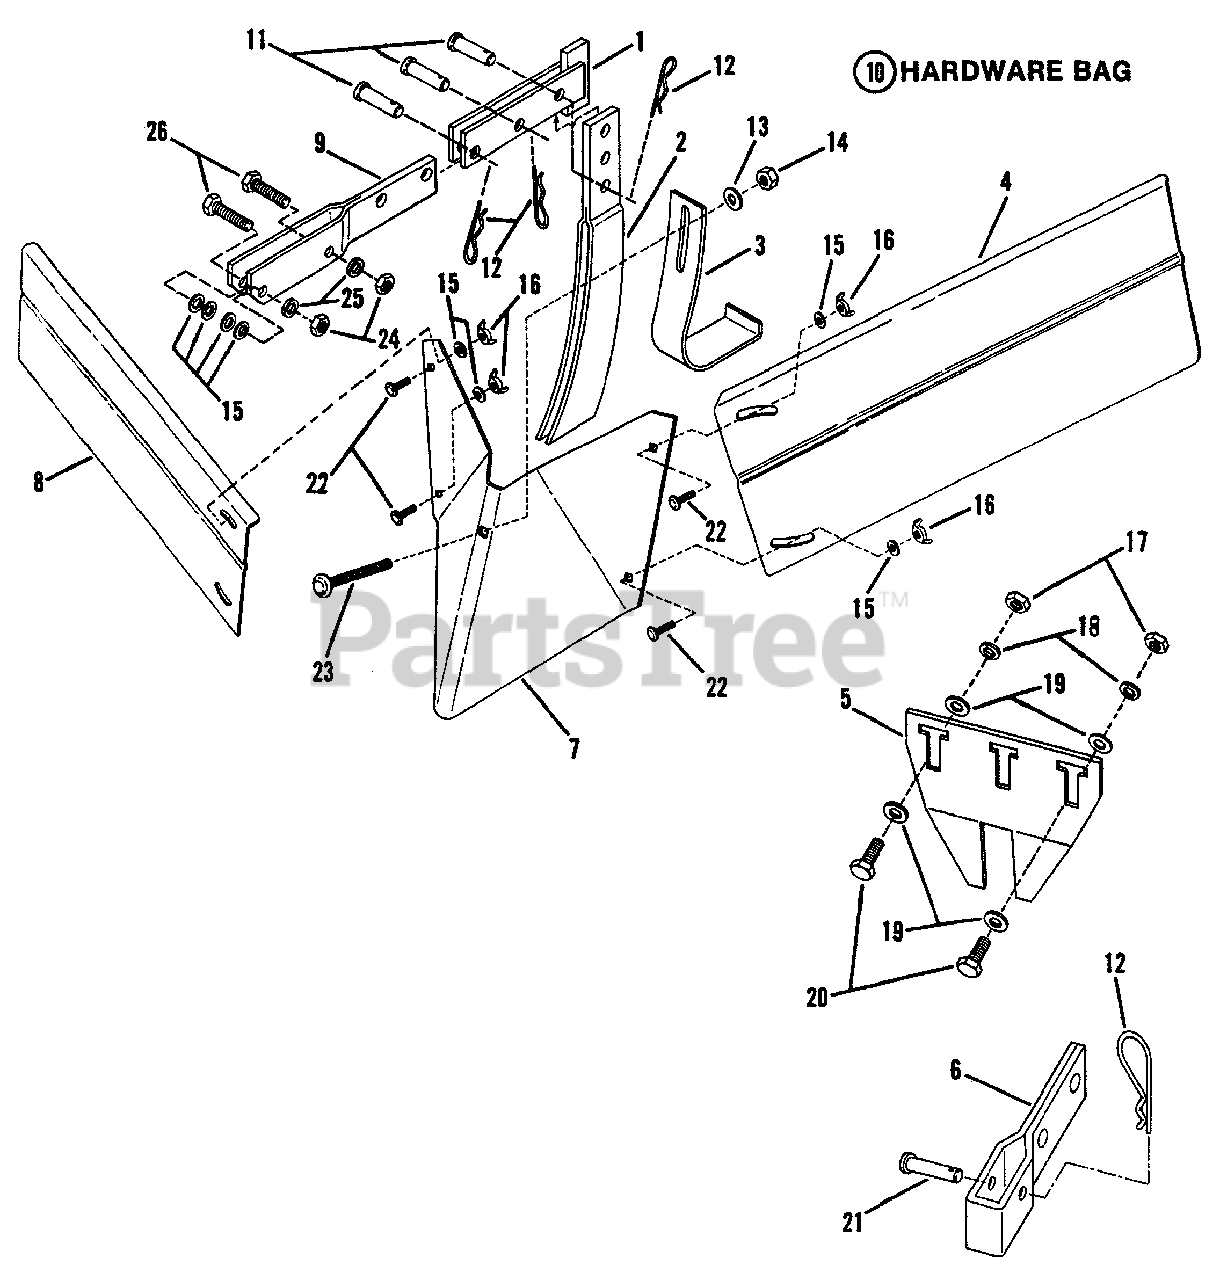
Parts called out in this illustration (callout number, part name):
1	DRAW-BAR
2	STRUCTURE, Standard
3	SKID-SHOE
4	WING, Left Side Hiller
5	CLEVIS, Support
6	BRACKET, Mounting
7	HILLER - FURROWER
8	WING, Right Side Hiller
9	BRACKET, Clevis
10	HARDWARE BAG
11	PIN, 1/2 x 1" Clevis
12	PIN, 1/8 Hair
13	WASHER, 1/2" Flat
14	NUT, 1/2-13 Hex
15	WASHER, 5/16 Flat
16	WING-NUT, 5/16-18
17	NUT, 3/8-16 Hex
18	WASHER, 3/8 Split Lock
19	WASHER, 3/8" Flat
20	SCREW, 3/8-16 x 3/4" Hex Head Cap, Grade 5
21	PIN, 3/8 x 1-1/2" Clevis
22	BOLT, 5/16-18 x 3/4" Square Neck Carriage
23	BOLT, 1/2-13 x 3-1/2" Square Neck Carriage, Grade 2
24	NUT, 5/16-18 Hex
25	WASHER, 5/16 Split Lock
26	BOLT, 5/16-18 x 1-1/2" Hex Head Cap, Grade 5
